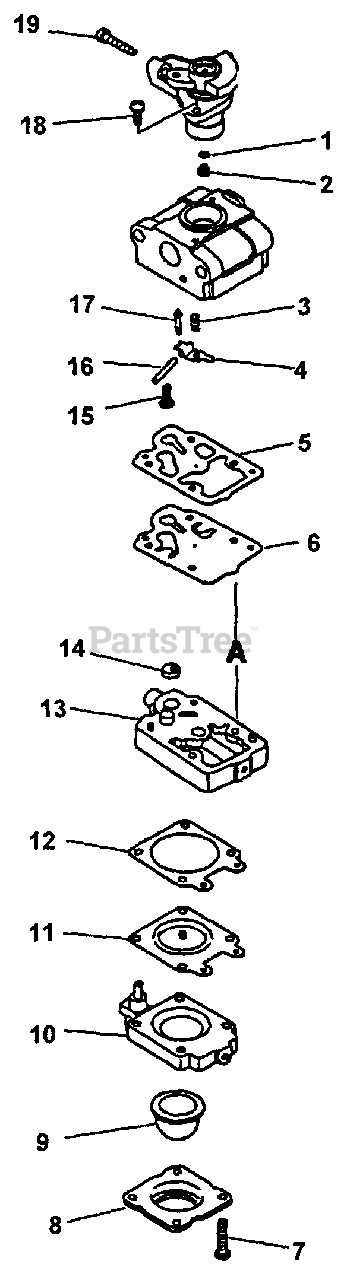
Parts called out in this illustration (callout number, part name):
1	O-RING
2	JET
3	SPRING, METERING LEVER
4	LEVER, METERING
5	GASKET, PURGE
6	DIAPHRAGM, PURGE
7	SCREW, PUMP COVER
8	RETAINER, PURGE BULB
9	BULB, PURGE
10	PURGE BASE ASSY
11	DIAPHRAGM, METERING
12	GASKET, METERING
13	BASE, PURGE
14	STRAINER
15	SCREW, METERING LEVER PIN
16	PIN, METERING LEVER
17	VALVE, INLET
19	SCREW, IDLE ADJUST
